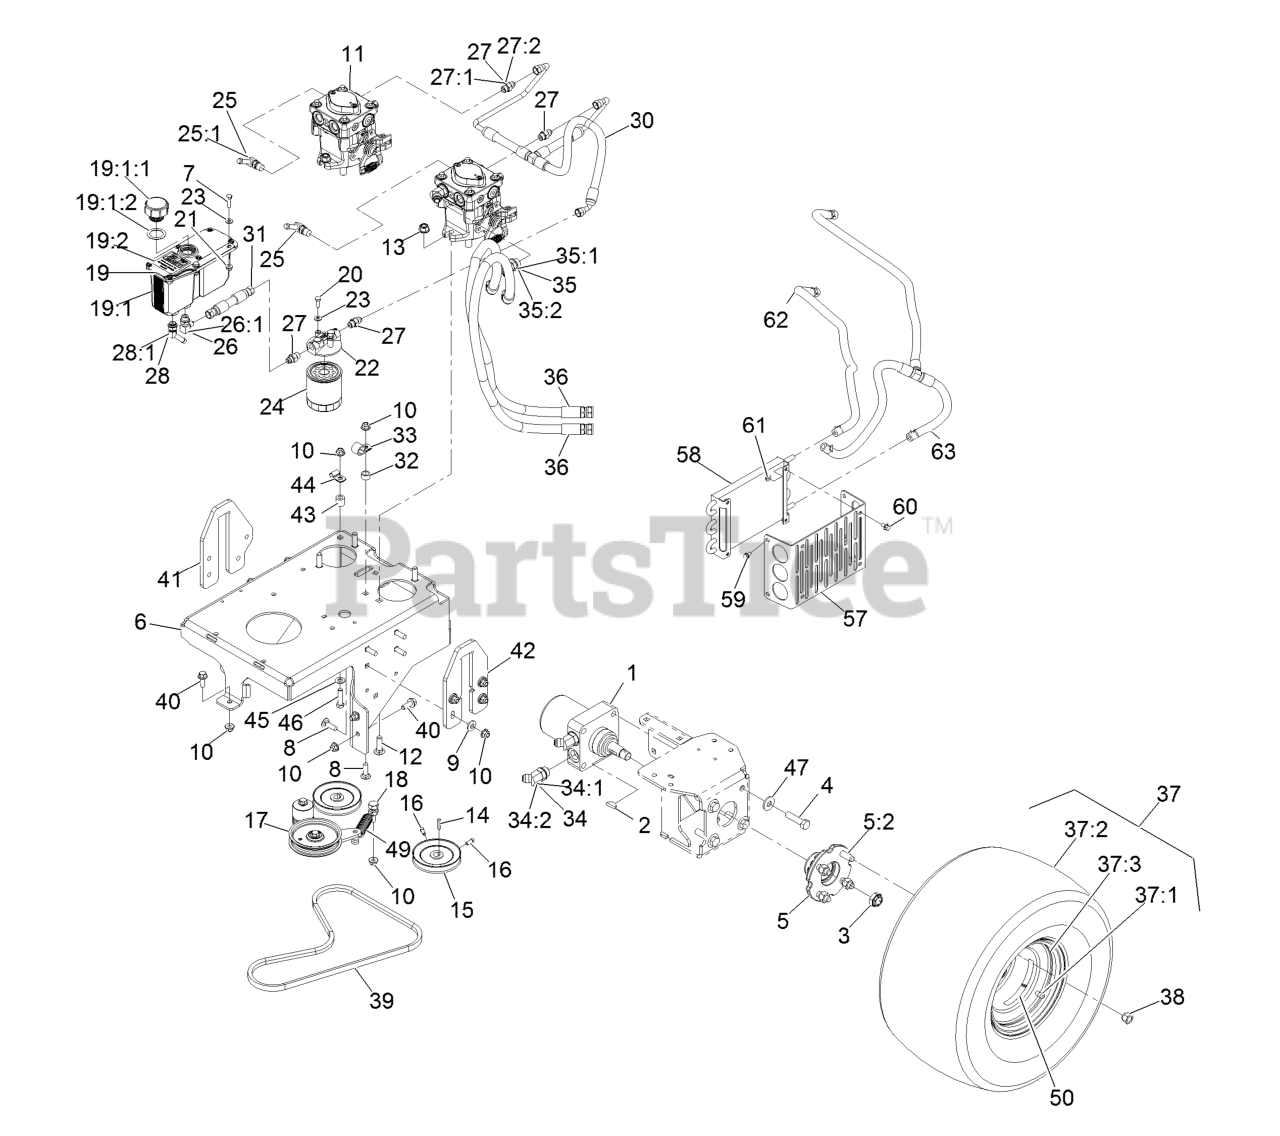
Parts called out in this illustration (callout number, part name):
1	MOTOR-WHEEL
2	KEY-WOODRUFF
3	NUT-LOCK
4	SCREW-HH
5	WHEEL HUB ASM
5:2	STUD-TYPE, DRIVE
6	BASE, ENGINE
7	SCREW-HH
8	BOLT-CARR
9	WASHER-BELLEVILLE
10	NUT-HF, NI
11	PUMP - HYDRAULIC
12	SCREW-HH
13	NUT-HF, NI
15	PULLEY-PUMP
16	SCREW-SET
17	PUMP IDLER ASM
18	ANCHOR, SPRING
19	RESERVOIR ASM
19:1	Reservoir-Hyd
19:1:1	Cap-Reservoir, HYD
19:1:2	GASKET-CAP
19:2	DECAL-HYDRAULIC TANK
20	SCREW-HH
21	NUT-HHF
22	HEAD-FILTER
23	WASHER-FLAT
24	FILTER-25 MICRON, BI-DIRE
25	FITTING-ELBOW, 90
25:1	O-RING
26	FITTING-ELBOW, 90 DEG
27	FITTING-STRAIGHT
28	FITTING-BARBED, 45 DEG
28:1	O-RING
30	HOSE ASSEMBLY - CHARGE
31	HYD HOSE ASM
32	SPACER-WHEEL
33	CLIP-LOOM
34	FITTING-HYD, 45 DEG
35	FITTING-HYD, 45 DEG
36	HYD HOSE ASM
37	WHEEL/TIRE ASM
37:1	RIM-8 INCH
37:3	Stem-Valve
38	NUT-LUG
39	BELT-V, LOWER PTO
40	SCREW-HHF 3/8-16 X 1
41	PLATE-LIFT, RH
42	PLATE, LIFT LH
44	CLIP-TUBE
45	WASHER-FLAT
46	SCREW-HH
47	WASHER-SPRING
49	SPRING-EXTENSION
57	BRACKET, COOLER MOUNTING
59	SCREW-HWH
60	SCREW-HHF
61	NUT-KEPS
62	HOSE-HYDRAULIC
63	HOSE ASM-HYD LP 3/8
